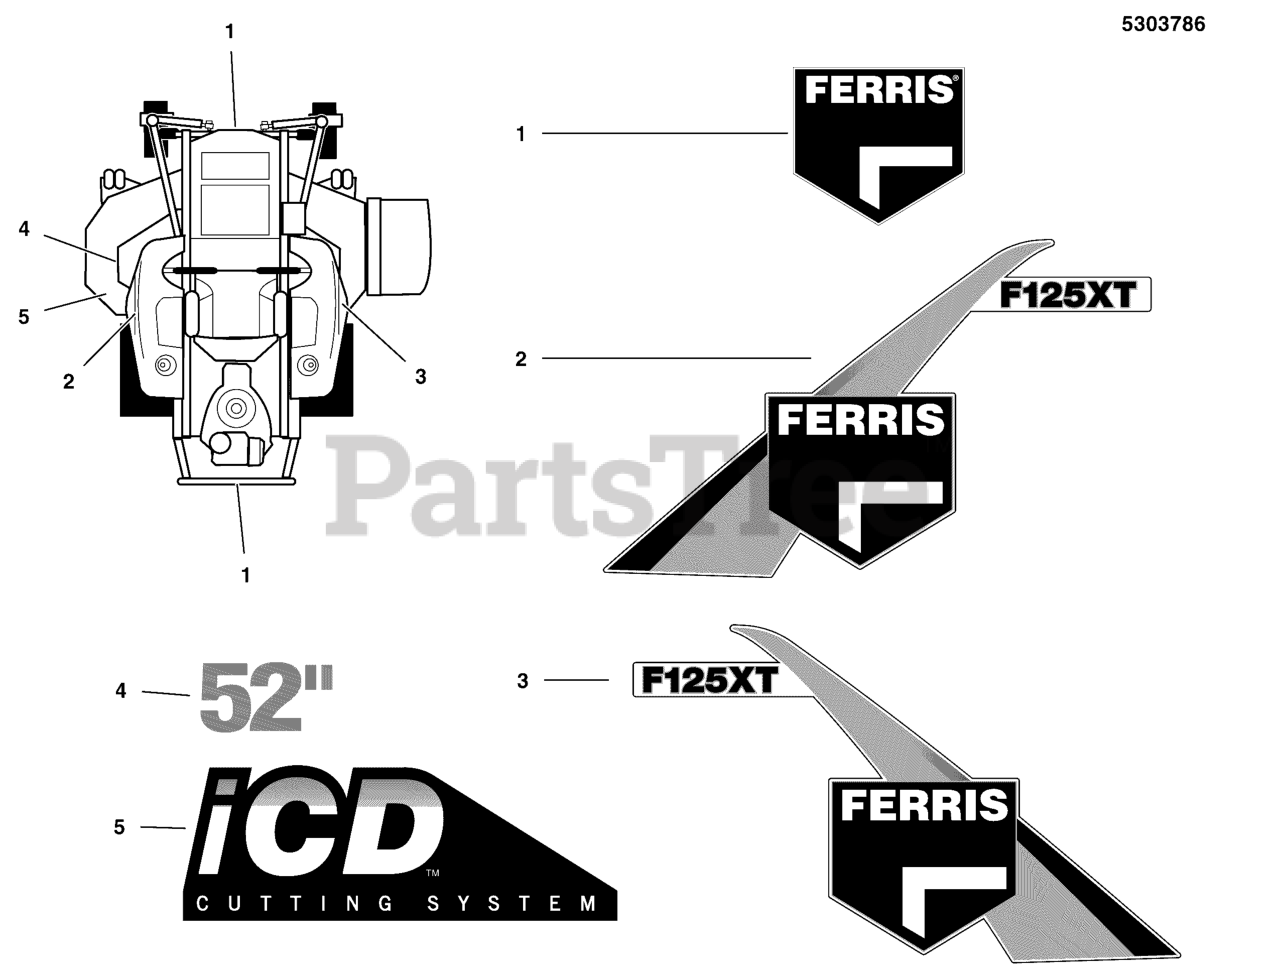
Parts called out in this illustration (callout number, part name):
1	DECAL, BRAND
2	DECAL, BADGE, LH, F125XT
3	DECAL, BADGE, RH, F125XT
4	DECAL, 52
5	DECAL, iCD CUTTING SYSTEM
